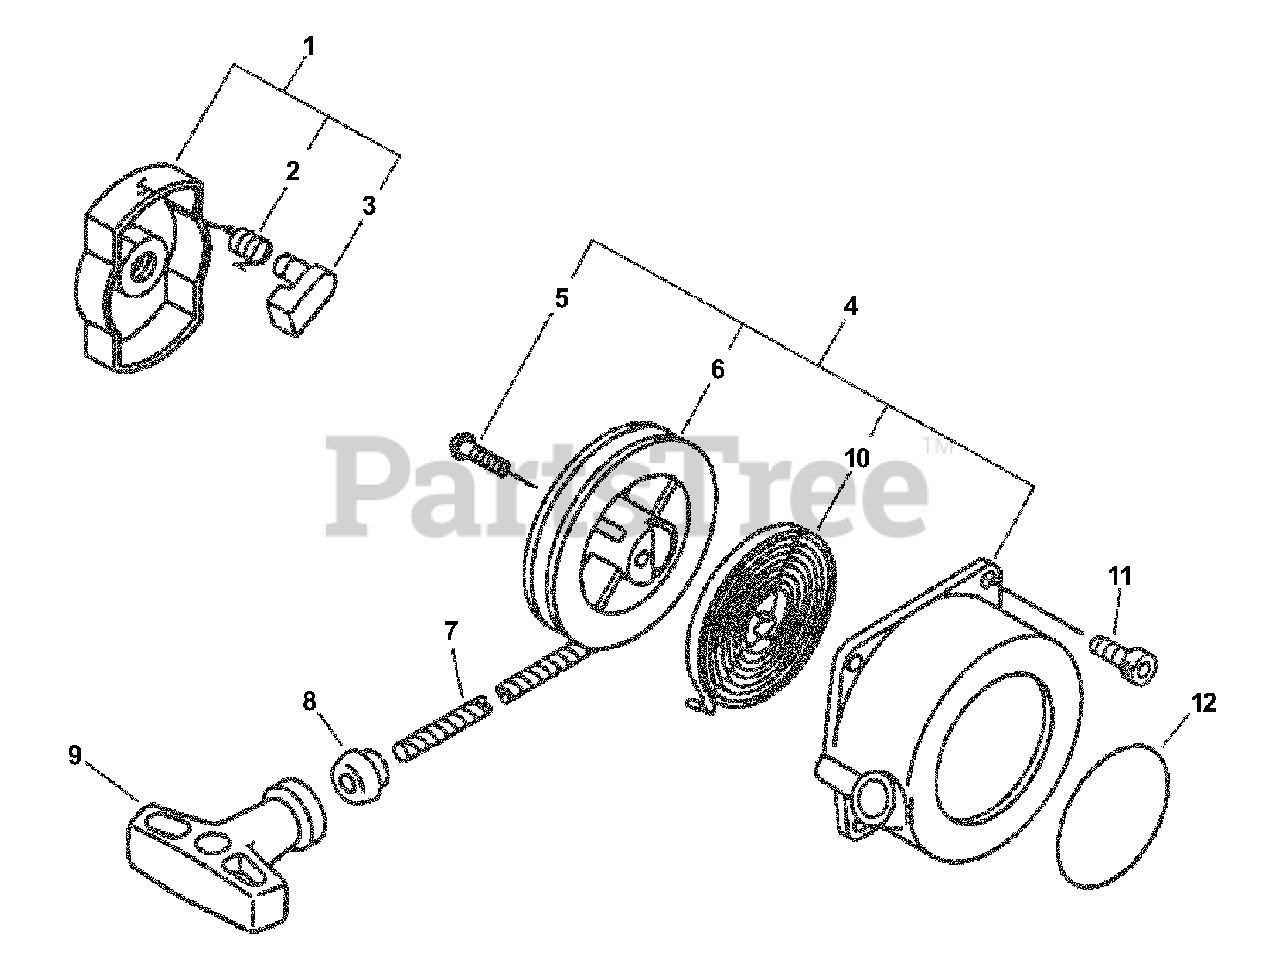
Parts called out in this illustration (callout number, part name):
1	STARTER PAWL ASSY
2	SPRING, RETURN
3	PAWL, STARTER - BLACK
4	STARTER ASSY
6	REEL, ROPE
7	ROPE, STARTER - 3.5X960
8	GUIDE, ROPE
9	GRIP, STARTER
10	SPRING, REWIND
11	SCREW - 4X16
12	LABEL - ECHO
